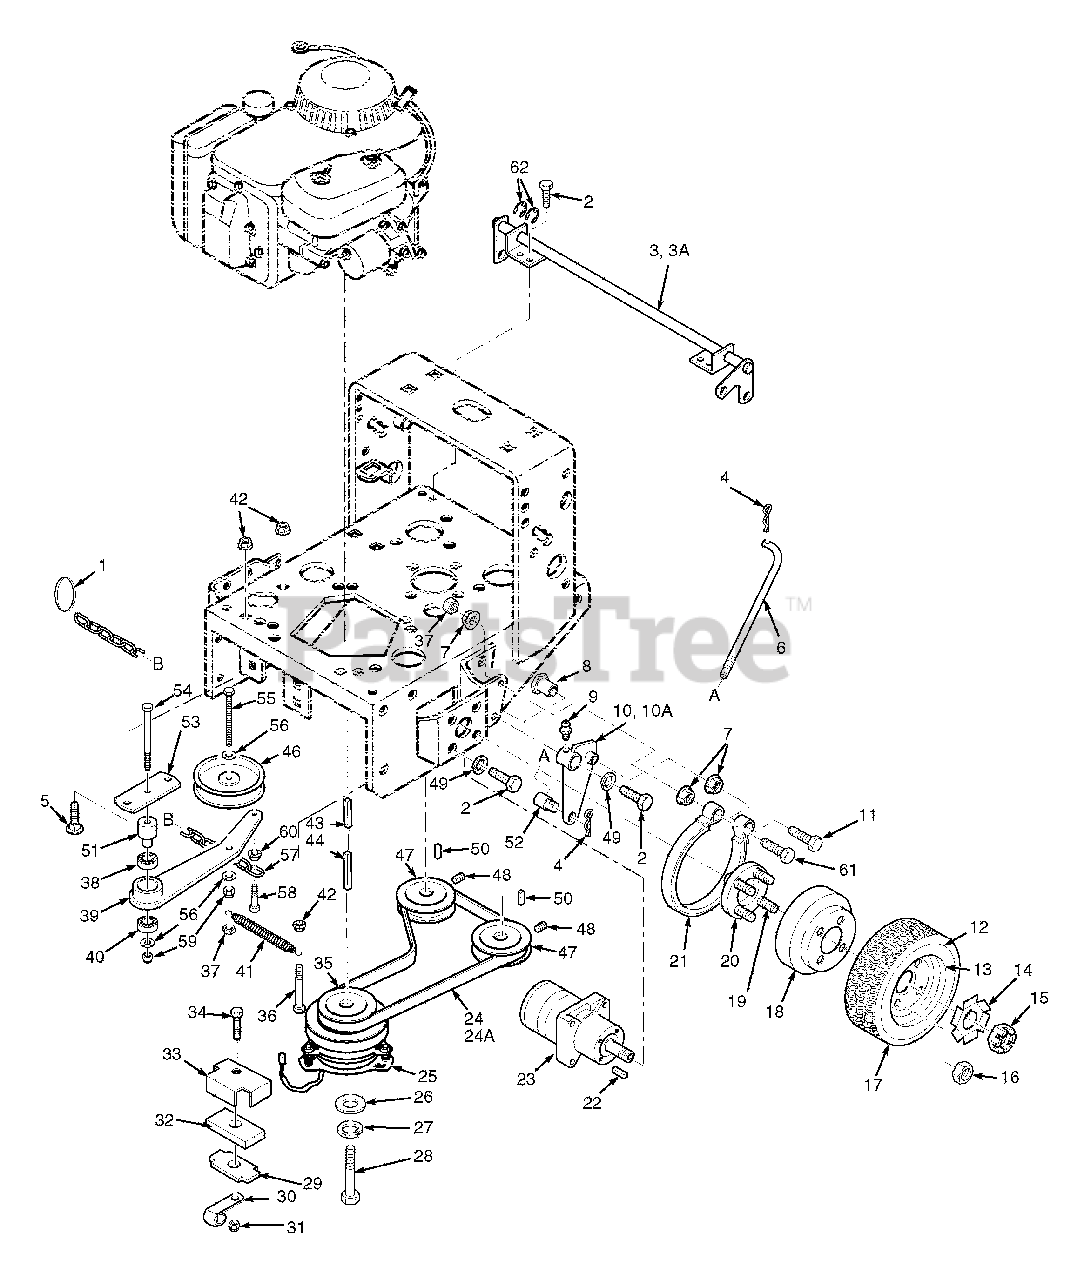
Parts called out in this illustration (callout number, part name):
1	Ring, Split
2	Bolt, 3/8-16 x 1" Hex Head
3	Brake Shaft Assembly (16" Small Frame)
3A	Brake Shaft Assembly (20" Large Frame)
4	Hair Pin Cotter, .094 x 1.62
5	Carrage Bolt, 5/16-18 x 3/4"
6	Rod, Brake Lower
7	Nut, 3/8-16 Serr. Flange
8	Bushing, Brake
9	Grease Fitting
10	Brake Actuator Wlmt., LH
10A	Brake Actuator Wlmt., RH
11	Bolt, 3/8-16 x 2-1/4"
12	Tire, 18 x 8.50, 4 ply
13	Rim Assy
14	Lock Washer, Wheel Motor
15	Hex Castle Nut, 3/4-28 UNEF
16	Nut, Lug
17	Wheel Assy. (Incl. #12 & 13)
18	Brake Drum
19	1/2-20 Serrated Bolt
20	Hub, Wheel
21	Brake Band, 7.5"
22	Key, 3/16" X 3/4" Woodruff
23	Wheel Motor
24	Belt, Pump Drive (16" Frame)
24A	Belt, Pump Drive (20" Frame)
25	Electric Clutch
26	Flat Washer .469 x 1.75 x .25
27	Lock Washer, 7/16"
28	Hex Head Bolt, 7/16-20 x 2-3/4"
29	Plate, Backing
31	Nut, 5/16-18 Elastic Stop
32	Rubber Pad, Clutch Stop
33	Retainer, Clutch Stop
34	Hex Head Bolt, 5/16-18 x 1-3/4"
35	Pulley, Pump Drive Engine
36	Hex Head Bolt, 5/16-18 x 2-3/4"
37	Nut, 3/8-16 Center Lock
38	Ball Bearings
39	Idler Arm Assembly
40	Ball Bearings
41	Spring, Pump Belt Idler
42	Nut, 5/16-18 Serr. Flange
43	Key, 1/4" x 1/4" x 1" Clutch Mtg.
44	Key, 1/4" x 1/4" x 2-3/4" Pulley Mtg.
45	Flat Washer, 3/8"
46	Pulley, Idler 4.5"
47	Pulley, Pump Shaft
48	Setscrew, 5/16-18 x 3/8"
49	Lockwasher, 3/8"
50	Key, 5.0 x 5.0 x 25mm
51	Pivot, Idler (Long)
52	Swivel Joint
53	Base, Idler Pivot
54	Bolt, Hex Head 3/8-16 x 3"
55	Bolt, Hex Head 3/8-16 x 2-3/4"
56	Flatwasher 3/8"
57	Chain
58	Bolt, Hex Head 1/4-20 x 1-1/4"
59	Nut, Hex Elastic Stop 3/8-16
60	Nut, Serrated Flange 1/4-20
61	Bolt, Hex Head 3/8-16 x 2-1/4"
62	Retaining Ring, 3/4" Ext. "E"
